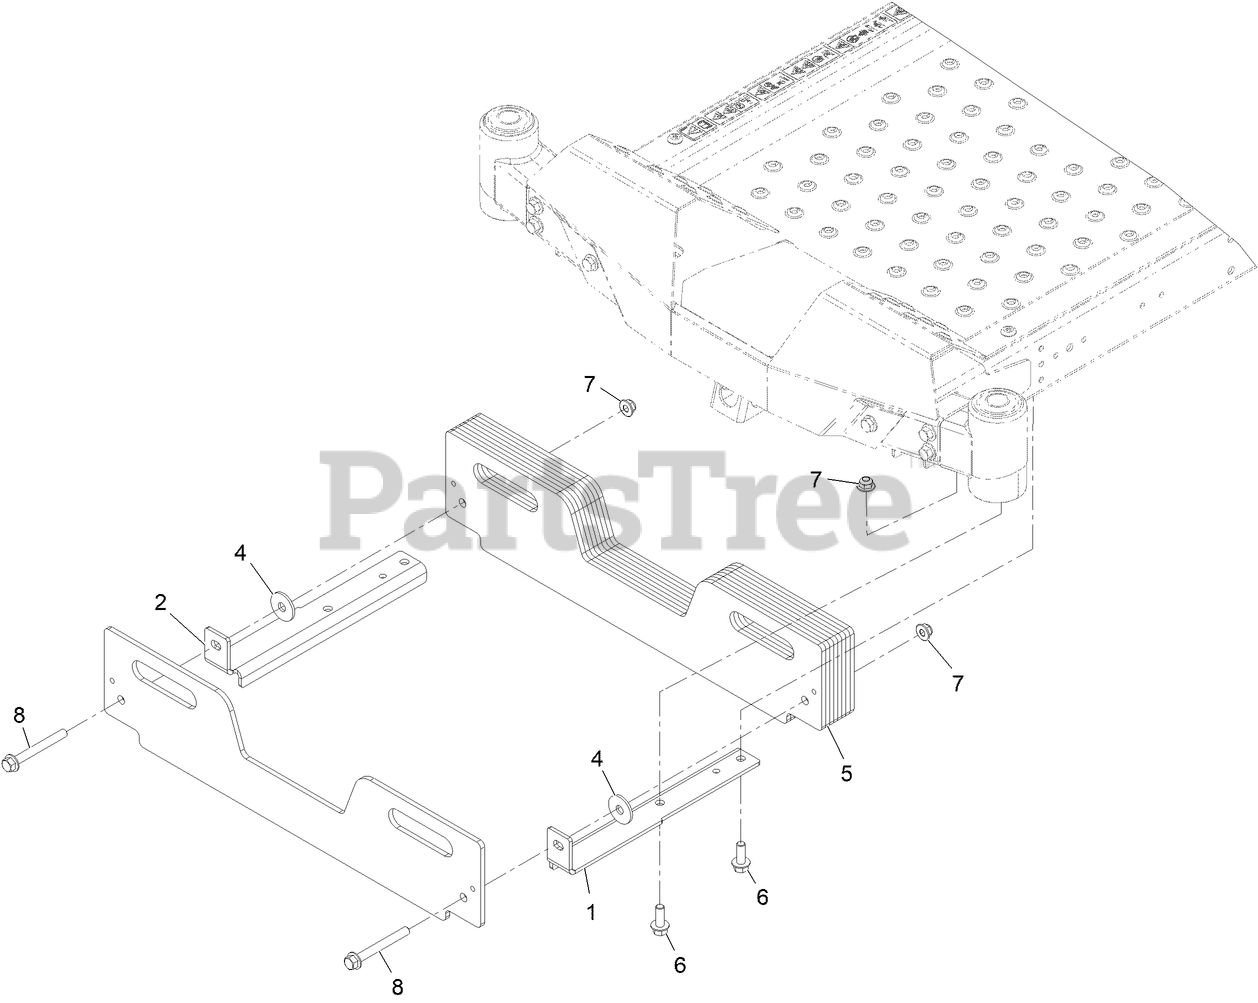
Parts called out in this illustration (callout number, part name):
1	Bracket-Weight, LH
2	Bracket-Weight, RH
5	Weight-Bagger
6	SCREW-HHF
7	Nut-HF, NI
8	Screw-HHF
